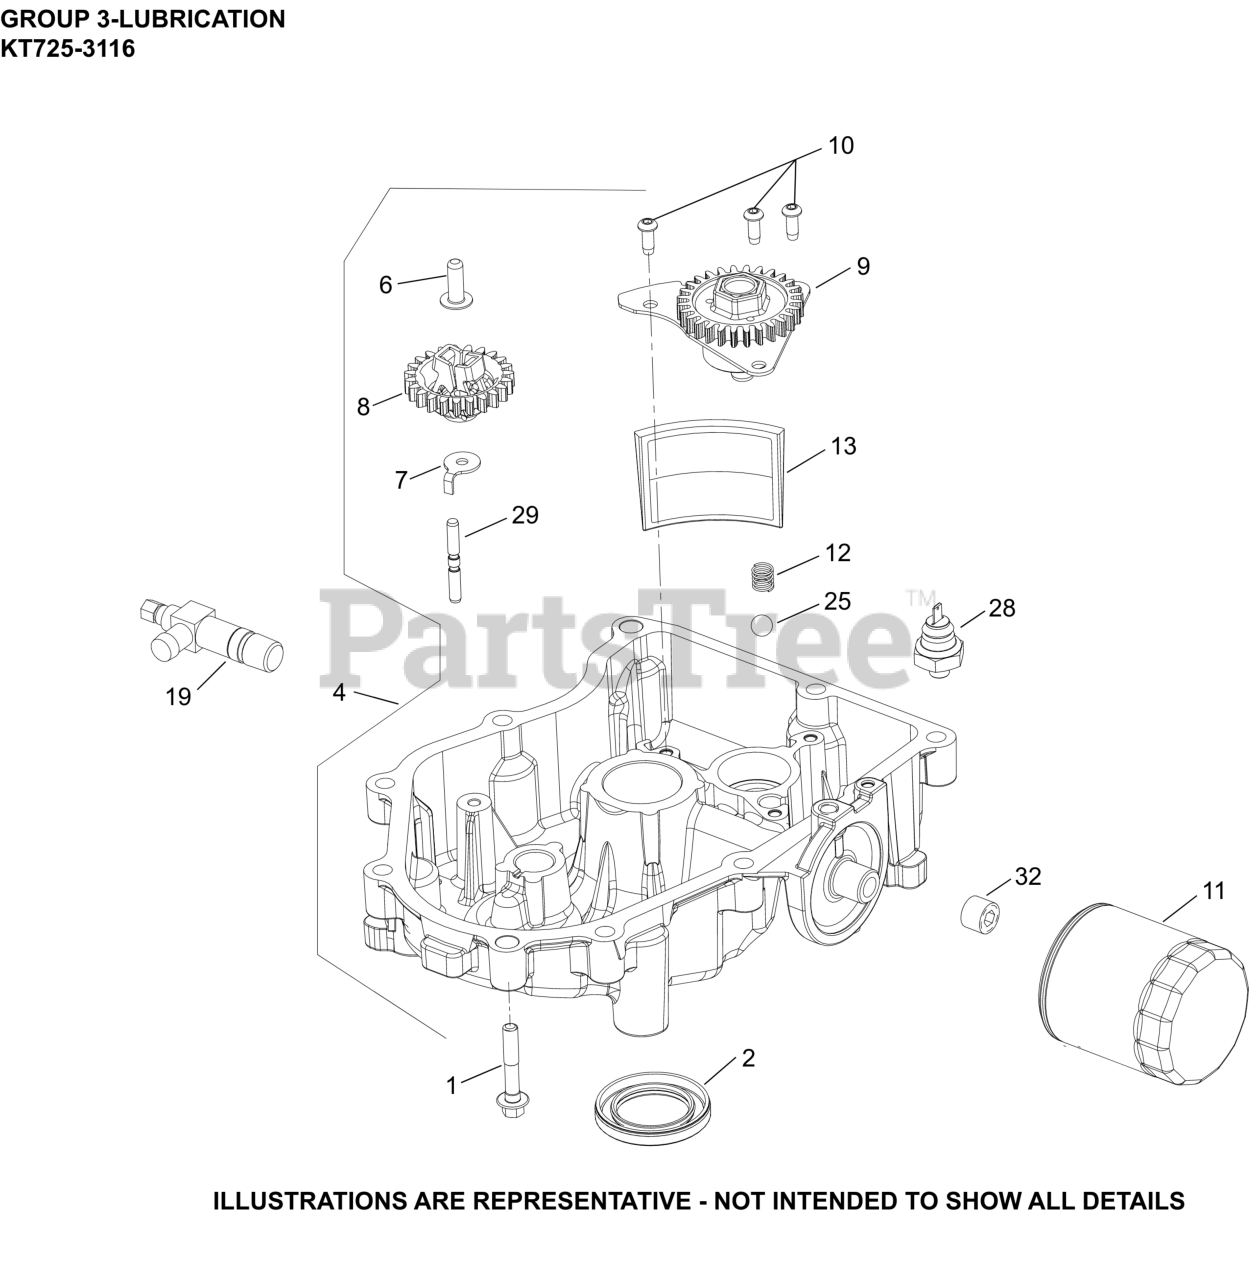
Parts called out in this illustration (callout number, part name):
1	SCREW, FLG M8X1.25X45
4	OIL PAN ASSEMBLY, (ROLLER BURNISHED)
6	PIN, GOVERNOR REGULATING
7	TAB, LOCKING
8	KIT, GOVERNOR GEAR
9	PUMP ASSEMBLY, OIL
10	SCREW, BUTTON HEAD
11	OIL FILTER
12	SPRING, COMPRESSION
13	SCREEN, OIL
19	VALVE, OIL DRAIN MEDIUM
25	PRESSURE RELIEF BALL
28	SWITCH, OIL PRESSURE(NC 3-6 PSI TO OPEN)
29	SHAFT, GOVERNOR GEAR
32	PLUG, PIPE CTSK 3/8"
